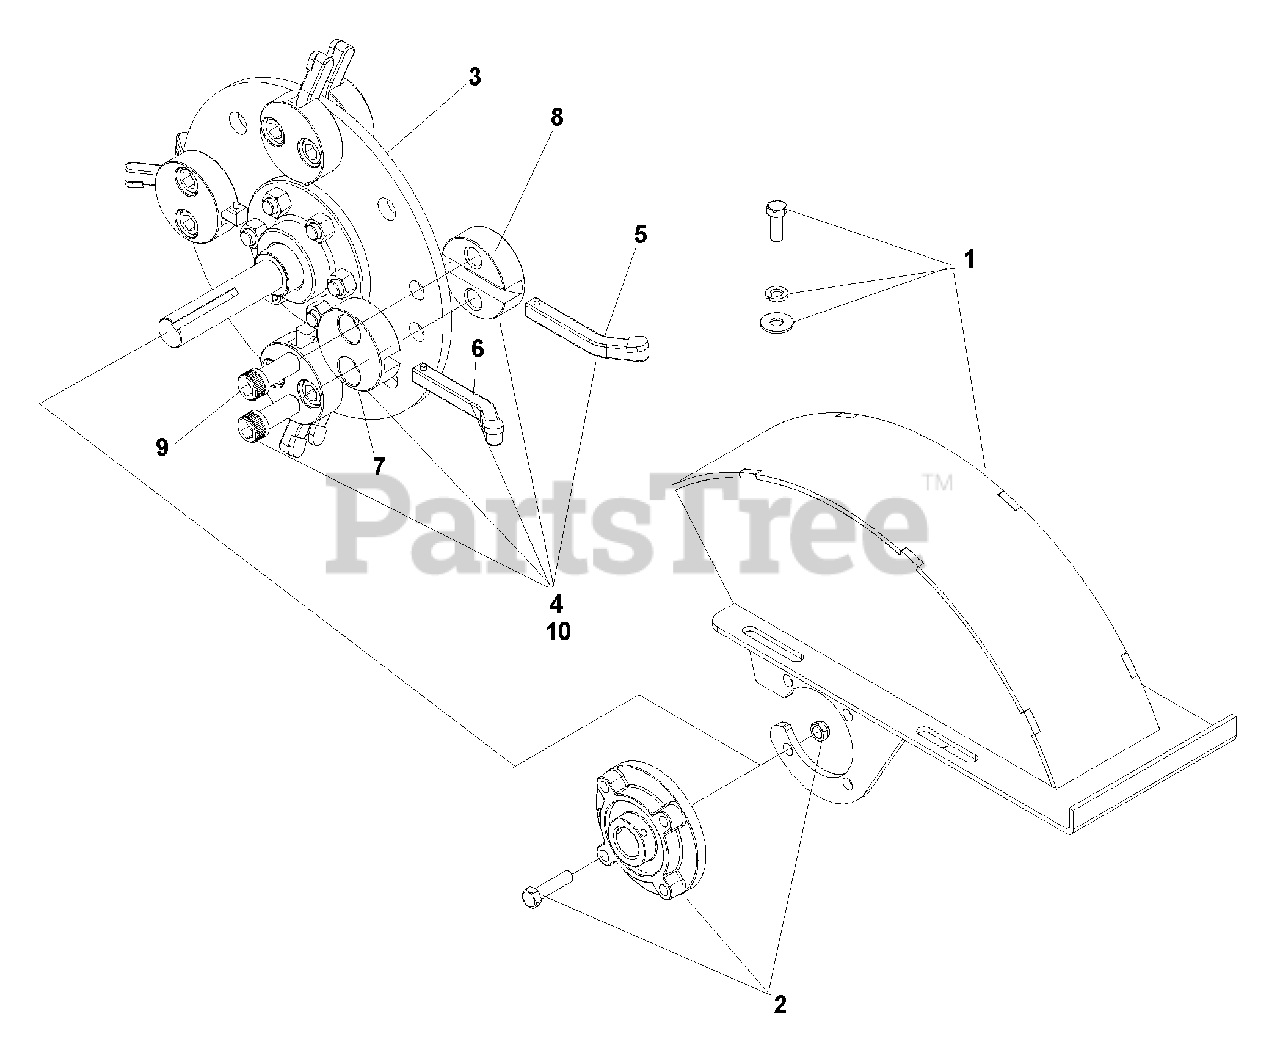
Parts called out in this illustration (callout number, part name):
1	KIT, CUTTING WHEEL SHROUD
1	SHROUD W/DECAL
1	BOLT, 3/8-16 X 1 (4 EA)
1	LOCKWASHER 3/8 (4 EA)
1	WASHER 3/8, FLAT (4 EA)
2	BEARING, FLANGE
2	BEARING (1 EA)
2	BOLT 3/8-16 X 1 3/4 (4 EA)
2	NUT 3/8, LOCK (4 EA)
3	CUTTING WHEEL ASSEMBLY (NO TEETH)
4	COMPLET SET OF CUTTING TEETH
4	COUNTER BORE POCKET (4 EA)
4	THREADED POCKETS (4 EA)
4	LEFT TOOTH (4 EA)
4	RIGHT TOOTH (4 EA)
4	SOCKET HEAD SCREWS (8 EA)
5	RIGHT TOOTH
6	LEFT TOOTH
7	COUNTER BORE POCKET
8	THREADED POCKET
9	SOCKET HEAD SCREW (2 EA) TWO SCREWS ARE REQUIRED PER POCKET
10	CUTTING TEETH, COMPLETE
10	RIGHT TOOTH (4 EA)
10	LEFT TOOTH (4 EA)
